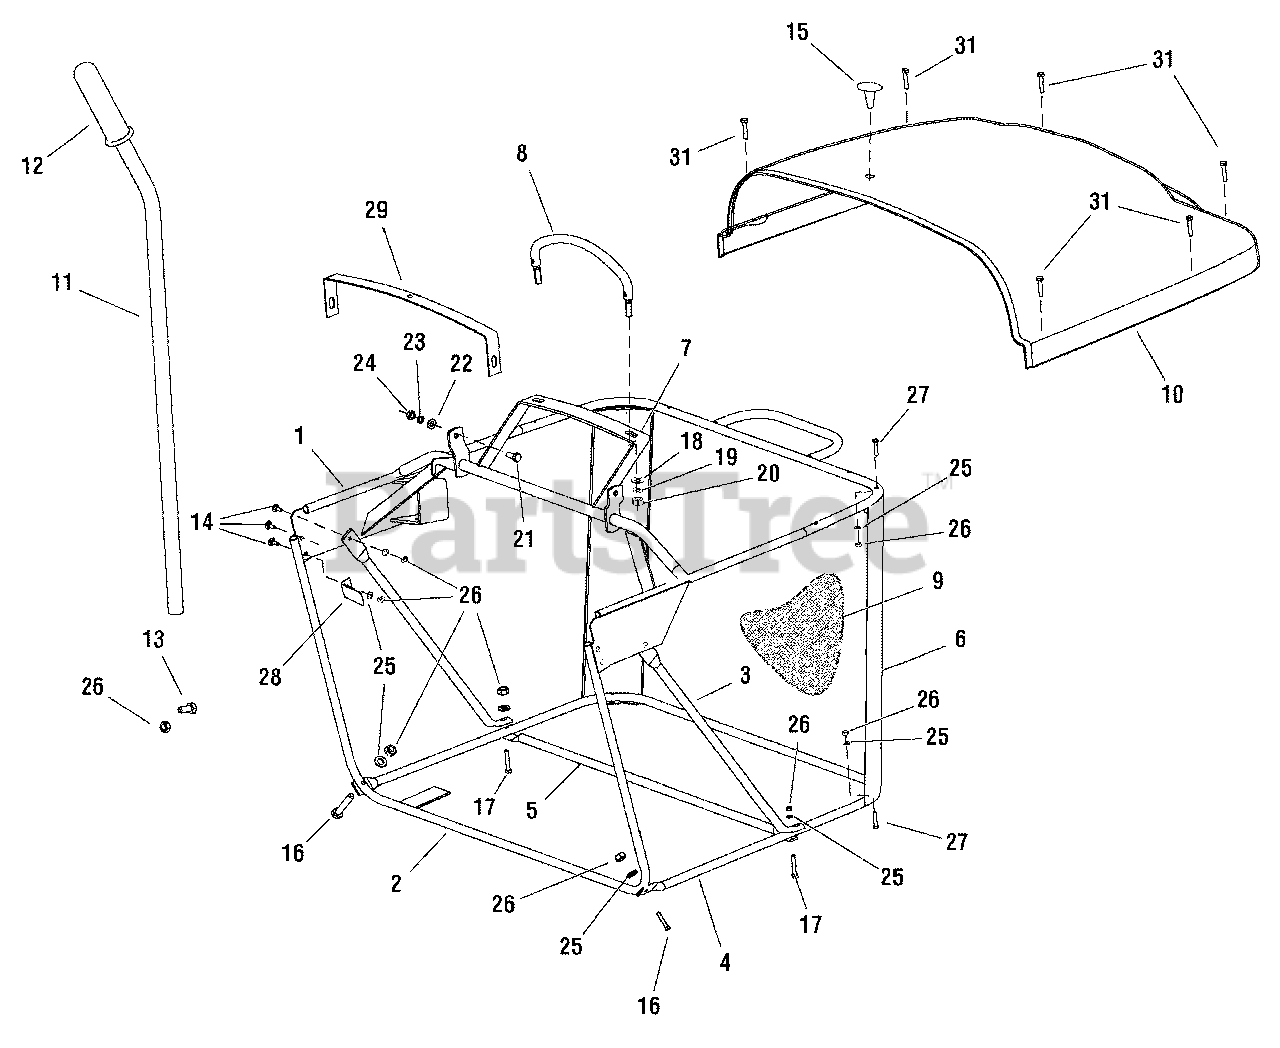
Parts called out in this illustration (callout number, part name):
1	FRAME, Top
2	TUBE, Front
4	TUBE, Bottom
5	TUBE, Connecting
6	REINFORCEMENT, Left
7	REINFORCEMENT, Right
8	HANDLE, Full
9	COAT, Fabric
10	TOP, Collector 0-7447-260
11	LEVER, Dumping
12	HANDLE, Rubber RC/M 25
13	BOLT, M5 x 12
14	BOLT, M5 x 16
15	PLUG, Plastic
16	BOLT, M5 x 30
17	BOLT, M5 x 35
18	WASHER, 10.5
19	WASHER, Lock 10
20	NUT, M10
20	NUT, Flange Lock, M10
21	BOLT, M8 x 20
22	WASHER, 8.4
23	WASHER, Lock 8
24	NUT, M8
24	NUT, Flange Lock, M8
25	WASHER, 5.3
26	NUT, M5
26	NUT, DIN 6926, M5
27	BOLT, M5 x 25
28	SPRING, Flat
29	REINFORCEMENT, Top
31	SCREW, 6.3 x 32 DIN 7504-K
